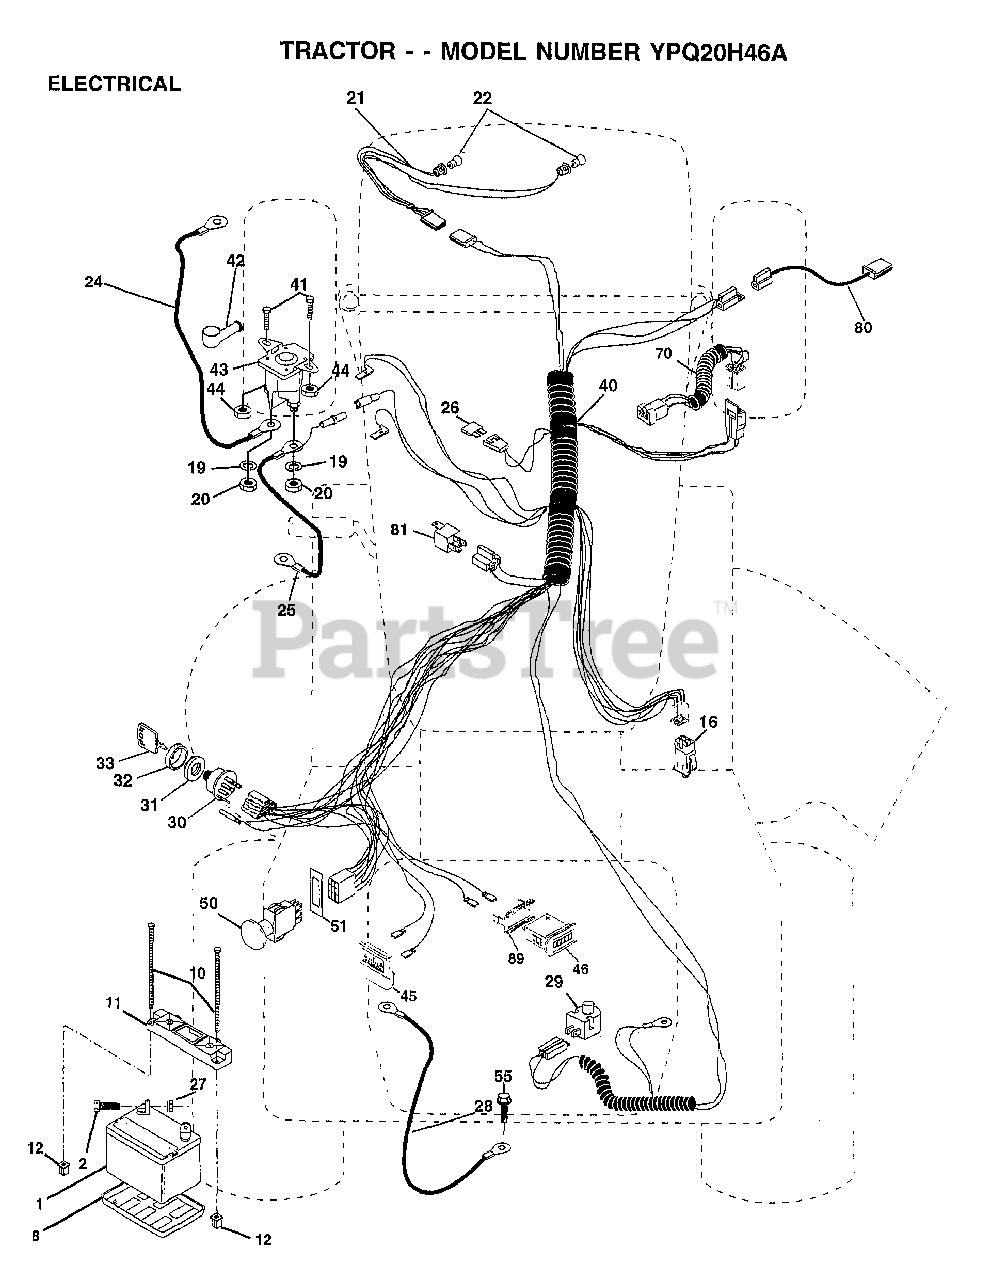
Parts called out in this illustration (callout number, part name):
2	BOLT LT
8	"TRAY T, BATTERY"
11	HOLDDOWN BATTERY
16	SWITCH INTERLOCK
20	NUT
21	HARNESS.ASM.LIGHT W/4152J
22	HEADLAMP BULB
24	"CABLE T, BATTERY"
25	CABLE.6GA.22W/16W
26	FUSE.15 AMP
27	NUT
28	CABLE.GRND.6GA.21
29	SWITCH.PLUNGER
30	SWITCH IGN 4POS
31	NUT IGNITION
32	COVER KEY SWITCH
33	KEY
40	HARNESS.IGNITION
41	BOLT HXHD FIN
44	NUT HXKEP 1/4X20
45	AMMETER
46	METER HOUR
50	PTO SWITCH.BLK
51	RING RETAIN PTO
55	SCREW LT
70	HARNESS.ENGINE.KOHL
80	HARNESS.CLUT.EVX.
81	RELAY ASSY T
89	BRACKET SNAP
